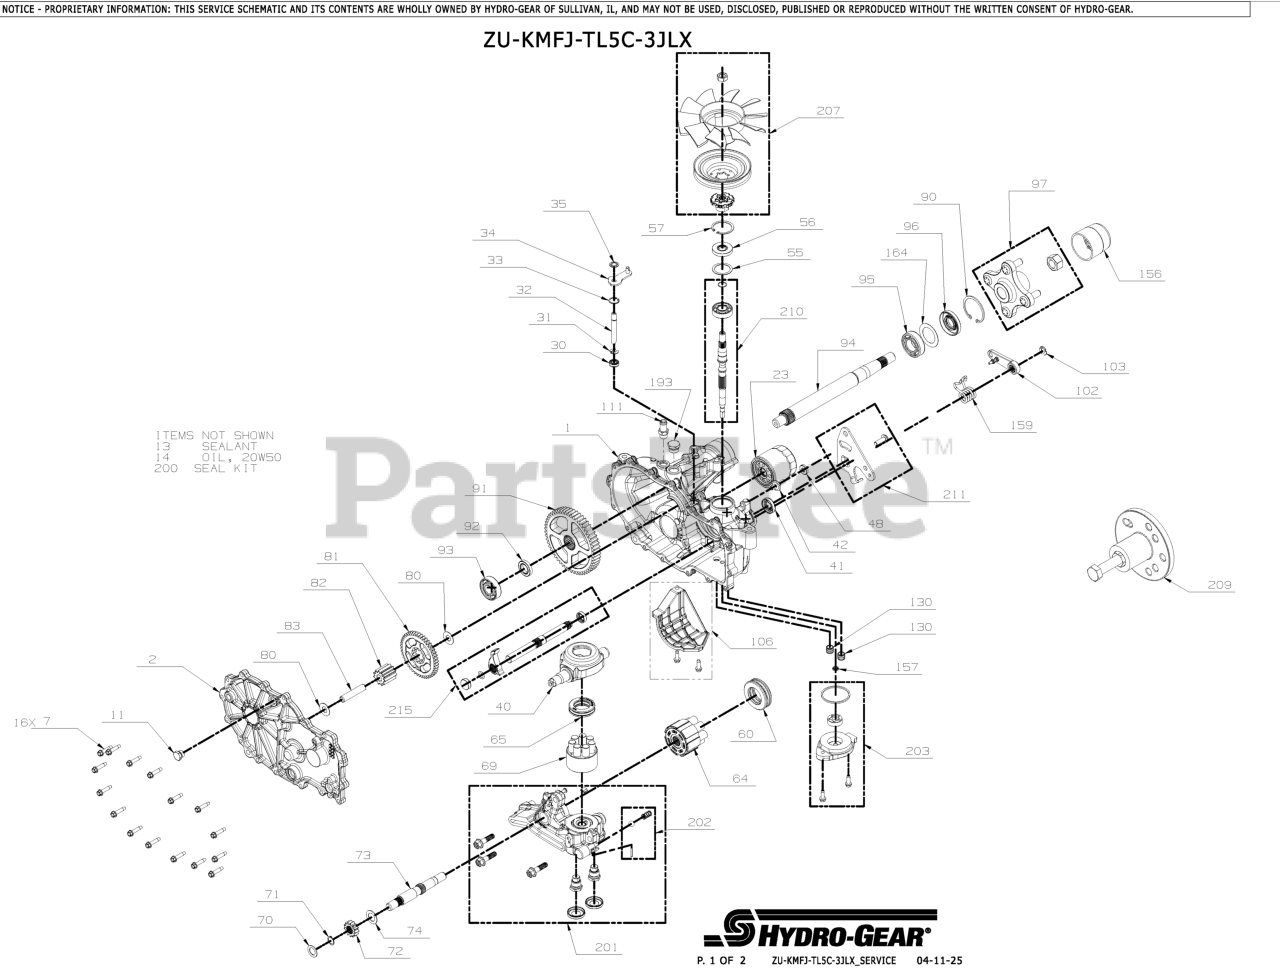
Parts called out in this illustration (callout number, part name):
1	KIT, MAIN HOUSING LH, CHARGE, CONTROL
2	KIT SIDE COVER, LH
7	SCREW,HEX WASHER 1/4-20X1.125
11	PLUG, EXTERNAL HEX VENT 9/16-18
13	SEALANT TUBE 10.1OZ.
14	FLUID, HYDRO 15W50 QT
14	FLUID, HYDRO 20W50 QT
23	FILTER, HYDRO-GEAR 2800 TRANS
30	SEAL, LIP .375 X .75 X .25
31	RING. RETAINING
33	RING, RET .750
34	HG BYPASS ARM (52370)
35	RING, RTNG .
40	TRUNNION, SWASHPLATE
41	SEAL, LIP 18X32X7
42	STUD. SHORT 5/16-24
48	SPACER
55	WASHER 1.23X1.56X.04
56	SEAL, LIP 17 X 40 X 7 HNBR
57	RING, RET 1.56 INT
60	HG THRUST BEARING (51462)
64	HG 16CC CYLINDER BLOCK (71579)
65	HG THRUST BLOCK (53502)
69	HG SEVEN PISTON BLOCK (71971)
70	WASHER .63X1.0X.05
71	RING, RET 62 EXT
73	SHAFT, MOTOR
74	WASHER .71 X 1.16 X .04
80	WASHER .5X1.0X.032
82	GEAR, 11T (STEEL)
83	PIN, JACKSHAFT
90	RING, RETAINING
91	GEAR, 54T
93	KIT, BEARING
94	SHAFT AXLE
95	BEARING, BALL 25.4 X 52 X 15
96	SEAL, LIP
97	KIT, HUB 4 BOLT
102	KIT, BRAKE ARM LEFT HAND
103	CLIP,BRAKE ARM HYDROGEAR 52027
106	KIT, FILTER GUARD
111	KIT, FITTING 1/2 BEADED 9/16
130	TUBE, CHARGE TRIPLE O-RING
156	CAP, AXLE
157	KIT, GEROTOR SEAL
159	SPRING TORS 1.01X1.17
164	WASHER, 1.355 x 2.035 x .021 FLAT
200	HG SEAL KIT (71976)
201	KIT CENTER SECTION, LH CHARGE
202	KIT, CHARGE RELIEF
203	KIT, CHARGE PUMP
207	KIT, FAN/PULLEY
209	HUB PULLER 5 BLT HYDGEAR 72320
210	INPUT SHAFT HG 71978
211	KIT, CONTROL ARM
215	OUTBOARD, RH ROT B / LH ROT A
